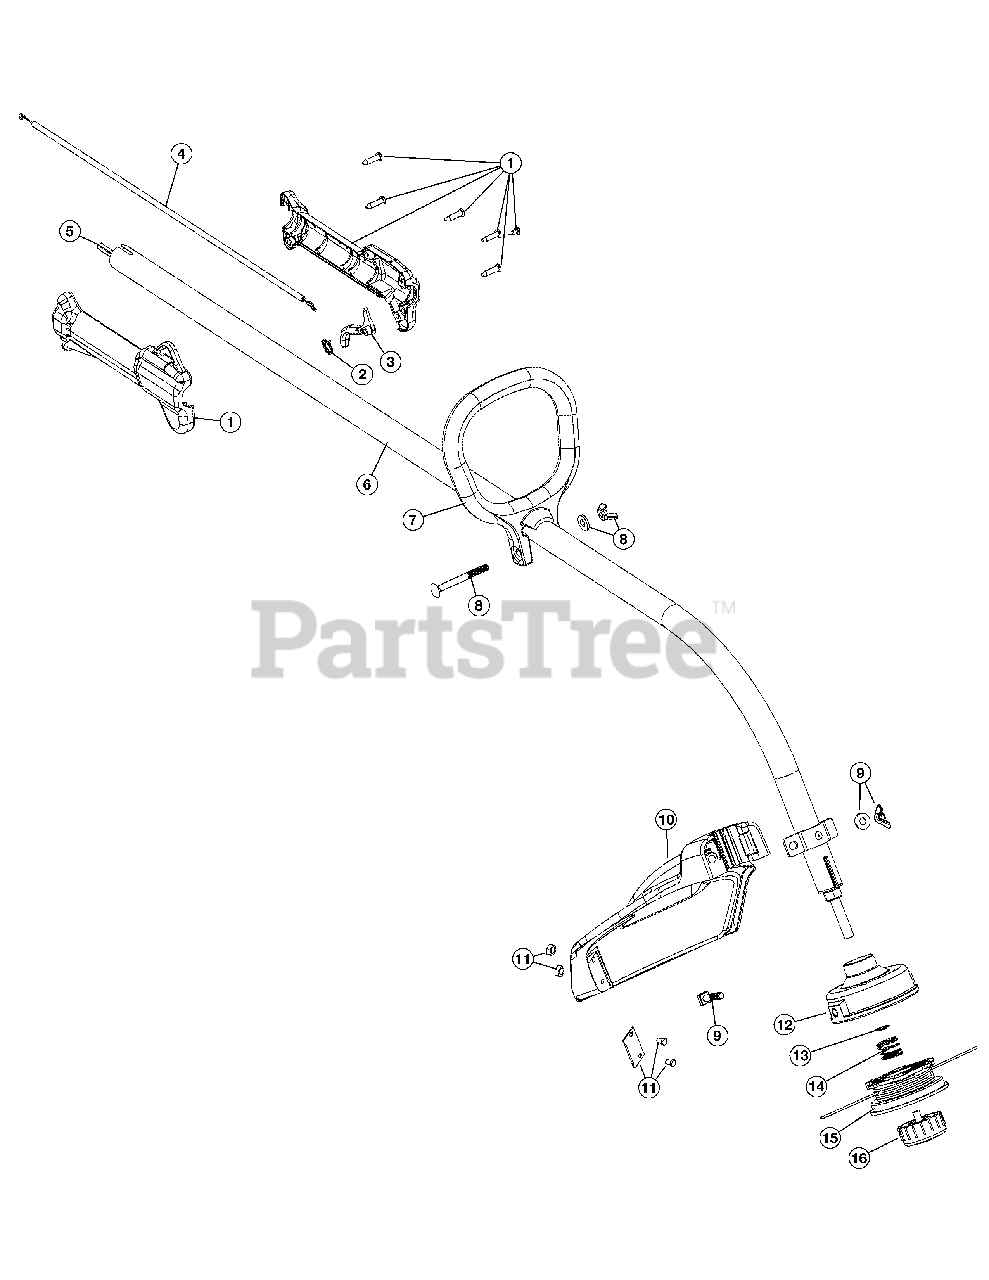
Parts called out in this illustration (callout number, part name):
1	Throttle Housing Assembly
2	Throttle Trigger Spring
3	Throttle Trigger
4	Throttle Cable
5	Flexible Drive Shaft
6	Drive Shaft Housing
7	D-Handle Assembly
8	D-Handle Hardware
9	Guard Mounting Hardware
10	Guard
11	Blade Assembly
12	Outer Reel
13	Retainer
15	Inner Reel
16	Bump Knob
